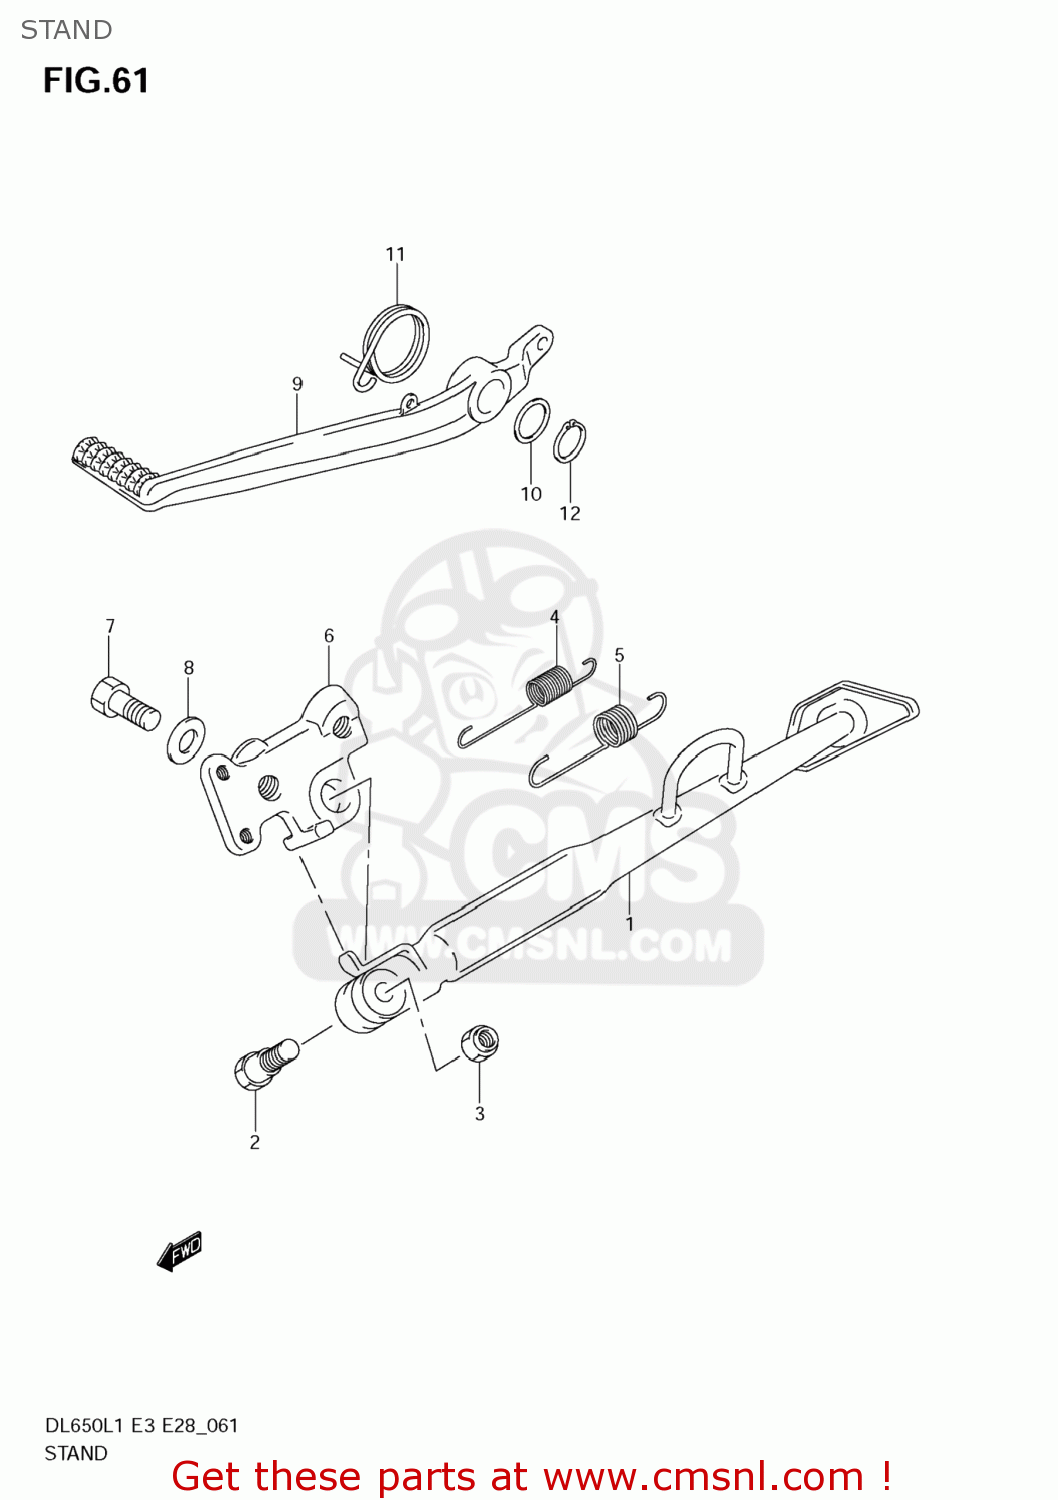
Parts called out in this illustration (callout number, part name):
1	STAND,PROP
2	BOLT(10X37.5)
3	NUT,PROP STAND
4	SPRING
5	SPRING
6	BRACKET, PROP STAND
7	BOLT(12X30)
8	WASHER(12.5X24X2.6)
9	PEDAL,BRAKE
10	WASHER(18X24X1)
11	SPRING
12	CIRCLIP
